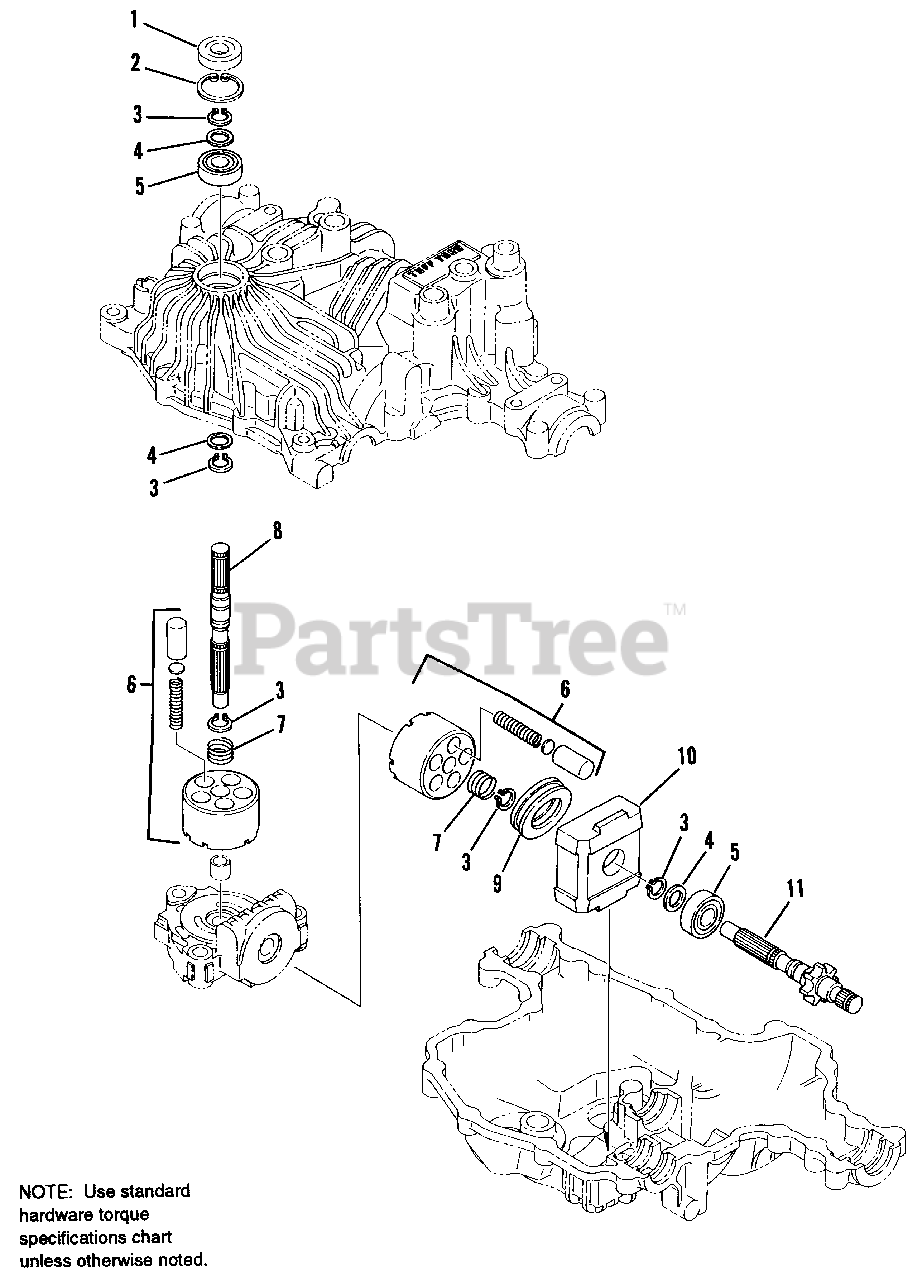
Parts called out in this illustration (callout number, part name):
1	SEAL
2	RING, Retaining
3	RING, Retaining
4	WASHER, 19/32 x 51/64 x 3/64
6	CYLINDER BLOCK
8	SHAFT, Pump
9	THRUST BEARING
10	RETAINER, Thrust Bearing
11	SHAFT, Motor
